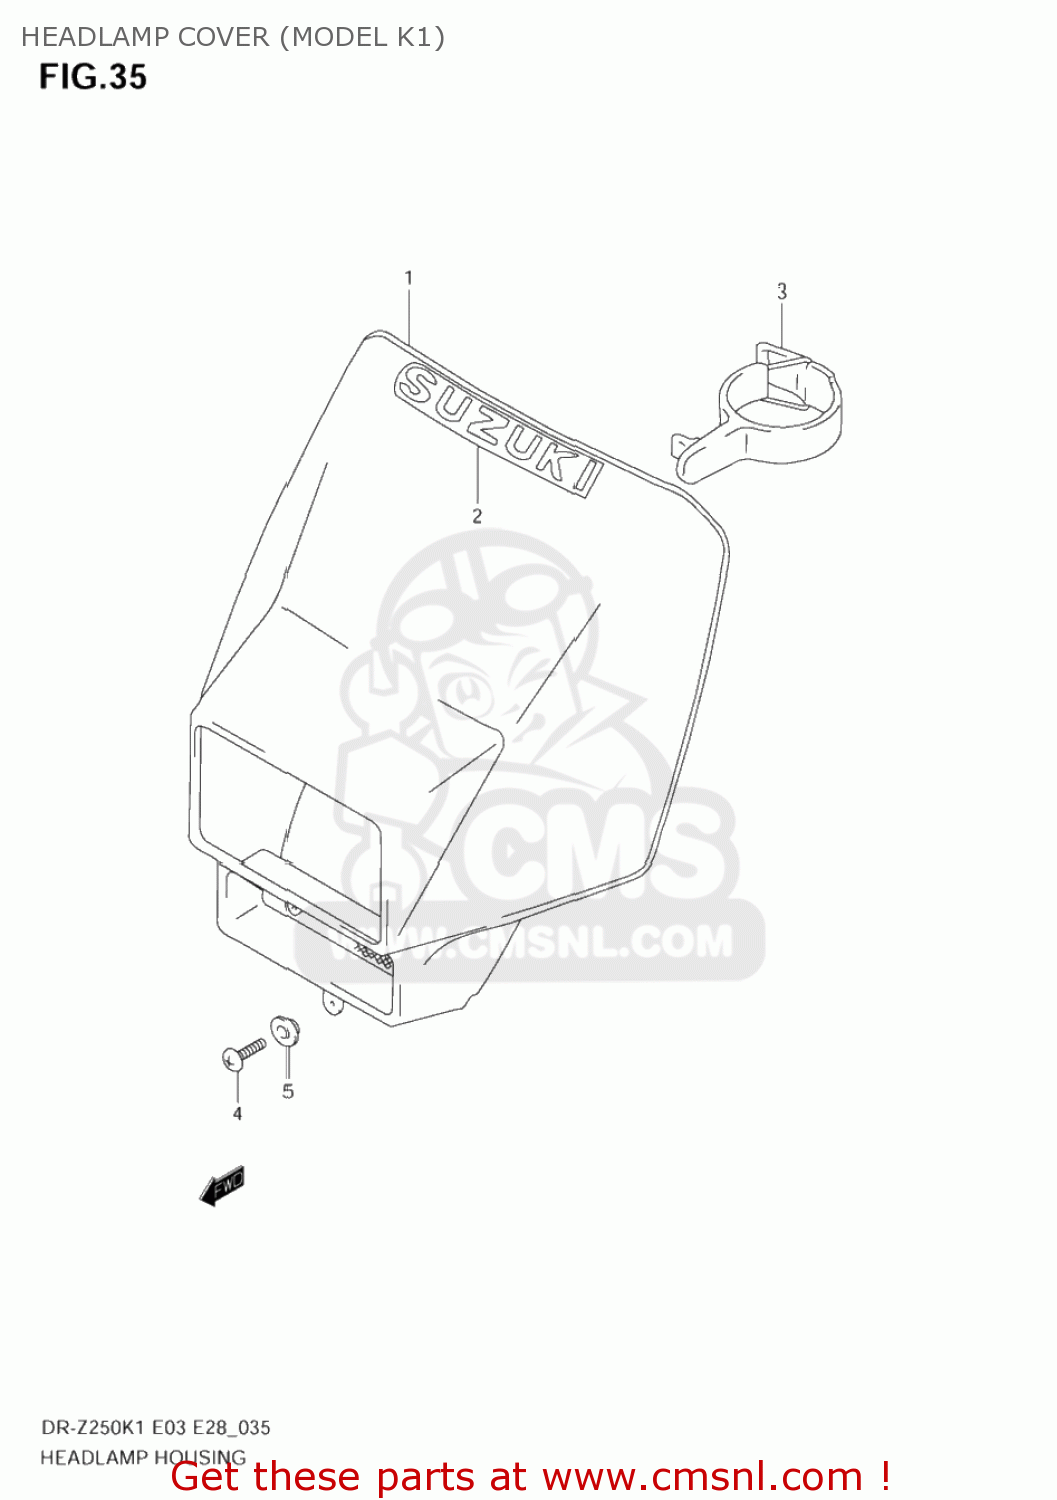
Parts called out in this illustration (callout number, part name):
1	COVER,HEADLAMP
2	EMBLEM,SUZUKI
3	BAND,HEADLAMP COVER
4	SCREW(5X12)
5	WASHER
